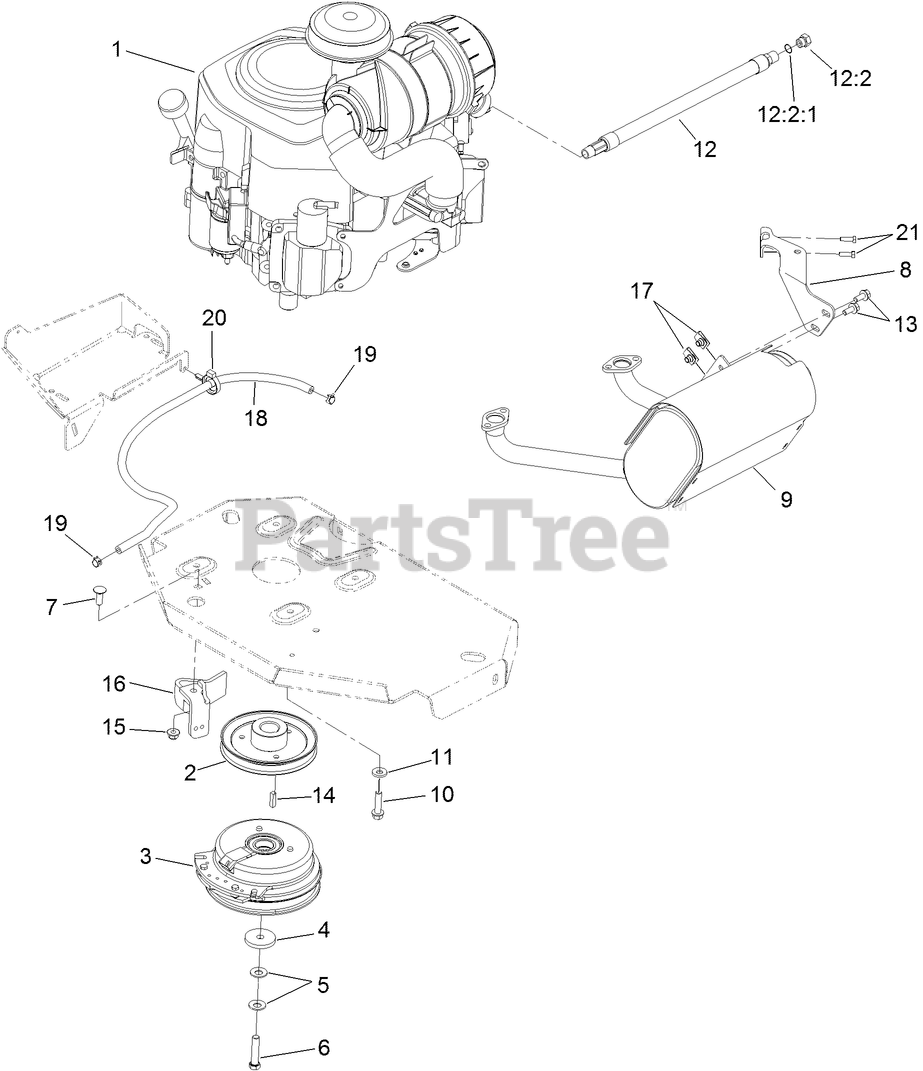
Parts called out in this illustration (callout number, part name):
2	SHEAVE
3	CLUTCH KIT
4	WASHER-CLUTCH
5	WASHER-SPRING
6	SCREW-HH W/LOCTITE
7	SCREW-CARR
8	MUFFLER BRACKET KIT
9	MUFFLER
10	SCREW-HWH
11	WASHER-BELLEVILLE
12	OIL DRAIN HOSE ASM
12:2	PLUG-HH
12:2:1	O-RING
13	SCREW-HHF
15	NUT-HF, NI
16	CLUTCH-ANCHOR
17	NUT-U
18	HOSE-FUEL
19	CLAMP-HOSE
20	CLAMP-HOSE
21	SCREW-HH
